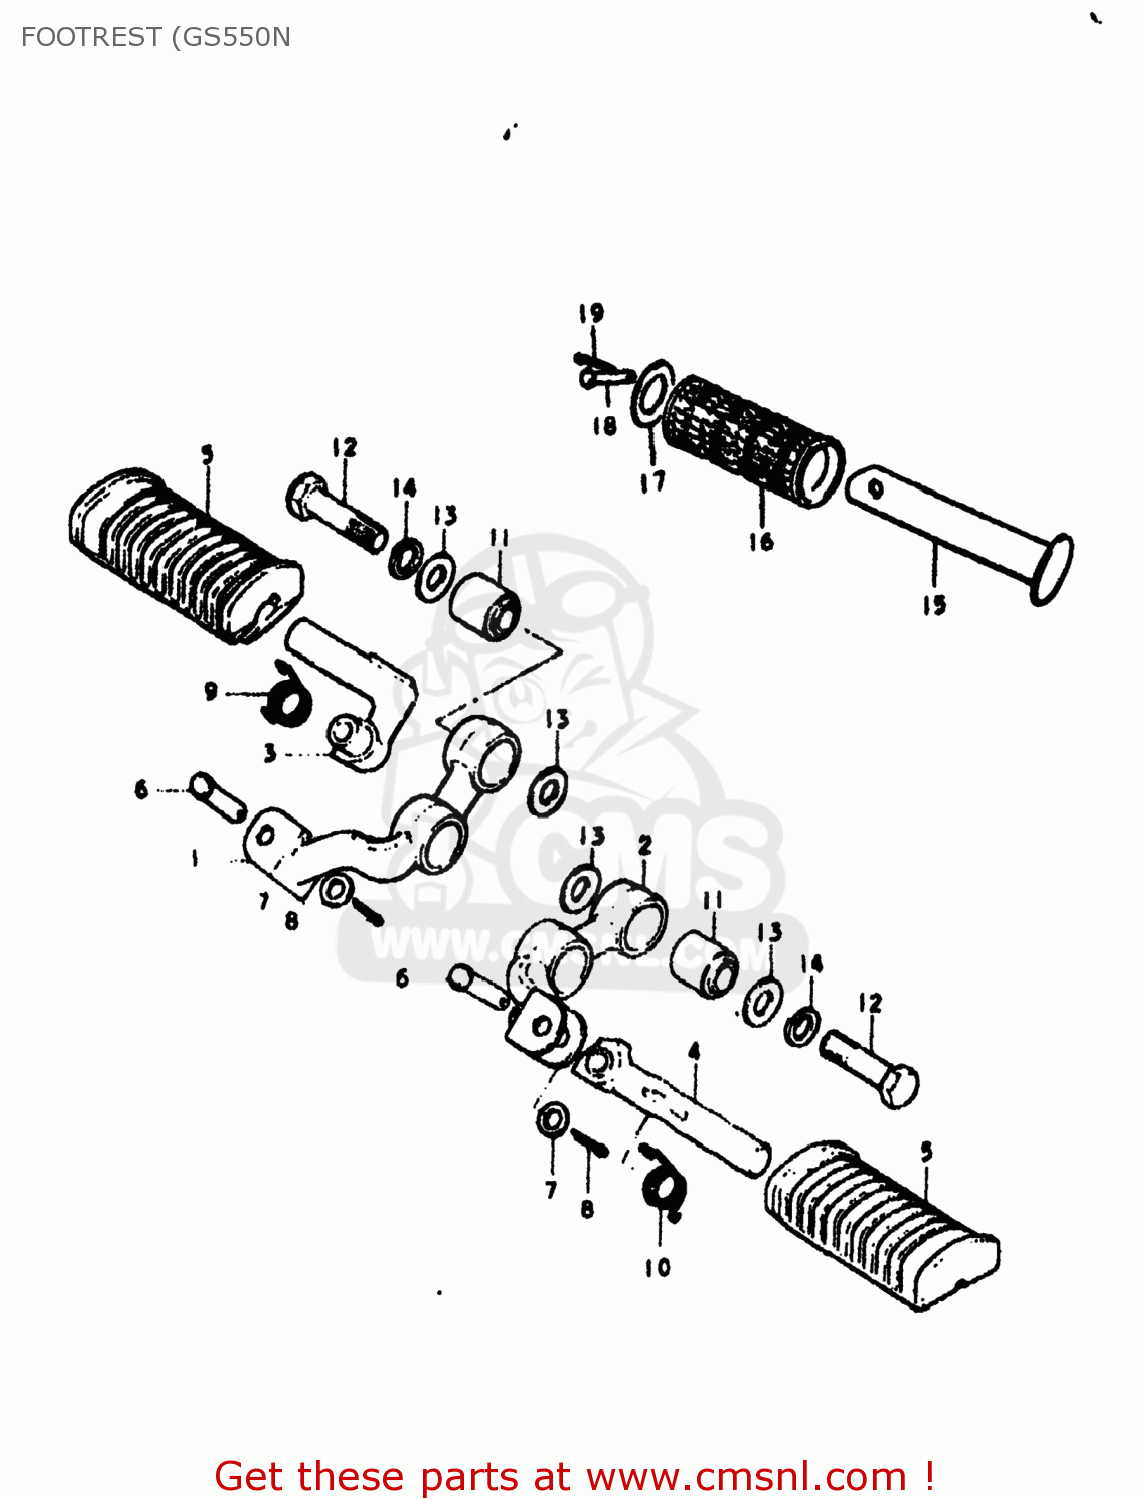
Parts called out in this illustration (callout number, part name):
1	BAR,FRONT FOOTREST,RIGHT
2	BAR,FRONT FOOTREST,LEFT
3	BAR,FRONT FOOTREST,RIGHT NO
4	BAR,FRONT FOOTREST,LEFT NO
5	RUBBER,FR FOOTREST
6	PIN
7	WASHER
8	PIN 20X20
9	SPRING
10	SPRING
11	BUSH
12	BOLT
13	WASHER (10.1X21X2.3)
14	LOCK WASHER
15	BAR,FOOTREST RUBBER
16	RUBBER,REAR FOOTREST
17	WASHER (19.5X32X2)
18	PIN
19	PIN
